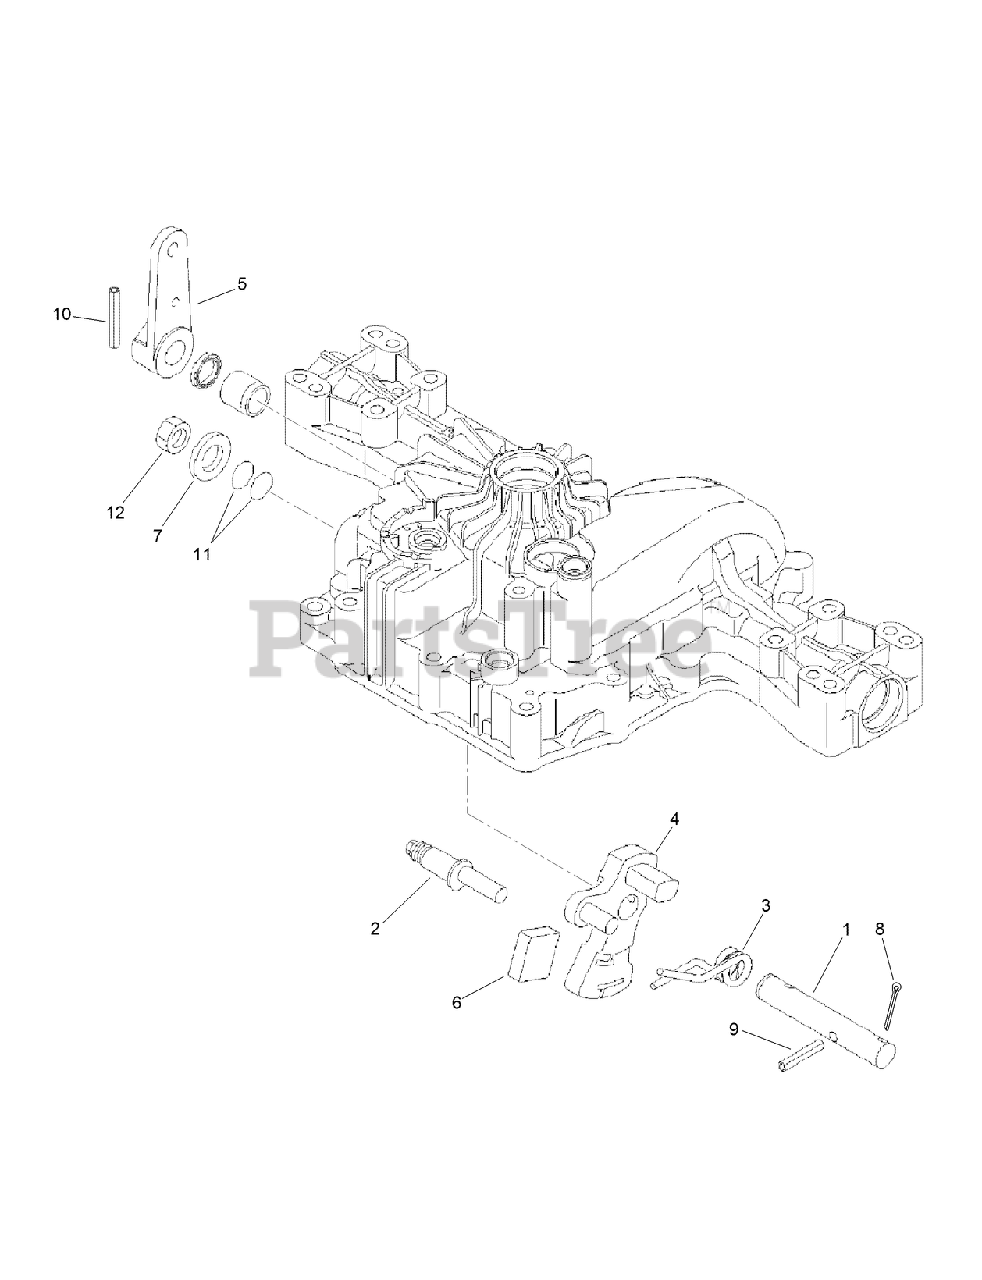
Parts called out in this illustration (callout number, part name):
1	SHAFT-CONTROL
2	FULCRUM-ECCENTRICITY
3	SPRING-TORSION
4	ARM-CONTROL
5	ARM-TRANSAXLE
6	PLATE-JERKY
7	WASHER
8	PIN-COTTER
10	PIN-ROLL
